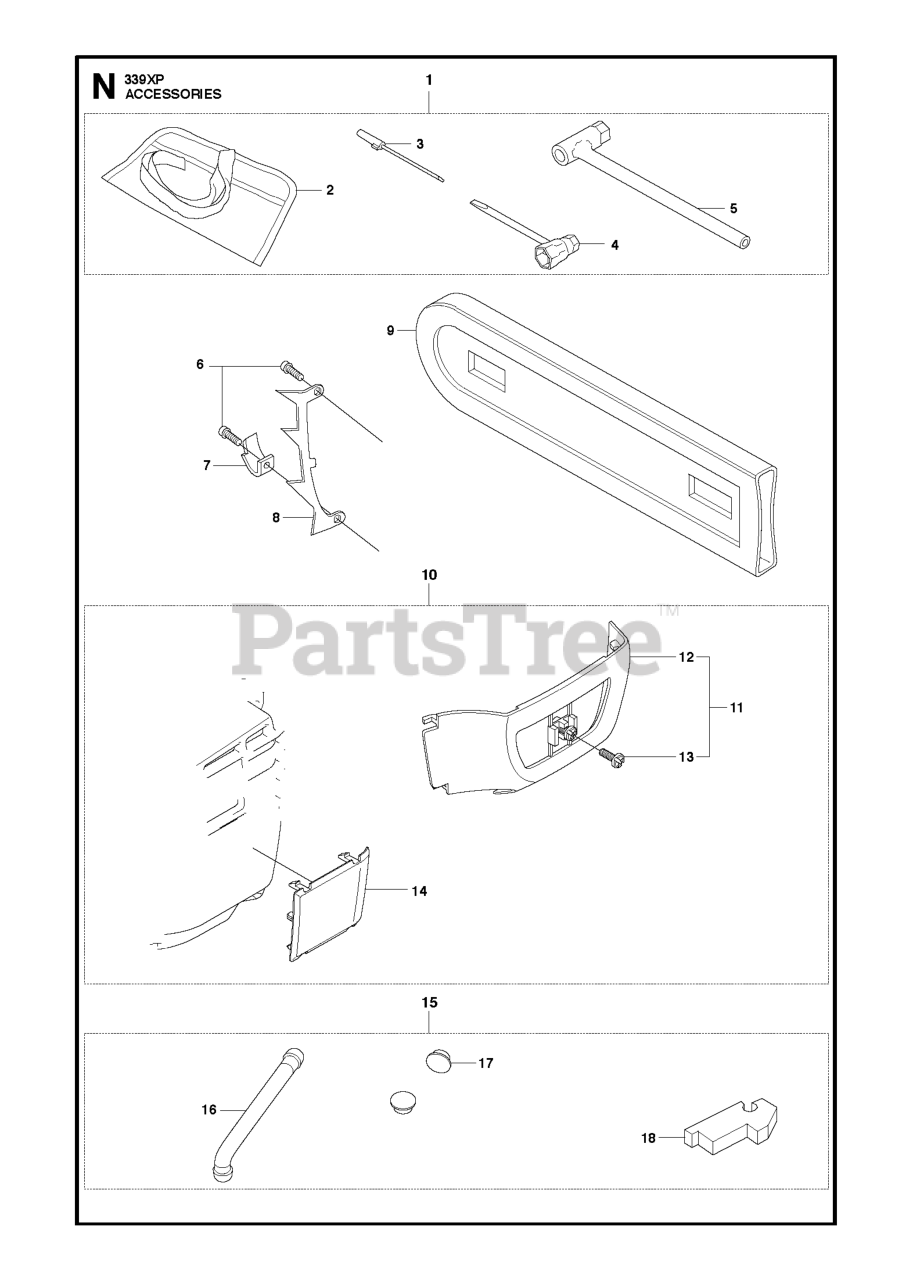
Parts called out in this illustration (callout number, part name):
1	TOOL KIT (3 PC)
3	SCREWDRIVER
4	COMBI TOOL
5	COMBI WRENCH
7	CHAIN CATCHER
8	FELLING DOG
9	BAR PROT/13-16""
10	WINTER COVER ASSY
11	WINTER COVER ASSY
12	WINTER COVER
15	WINTER SET
18	FOAM INSULATOR
